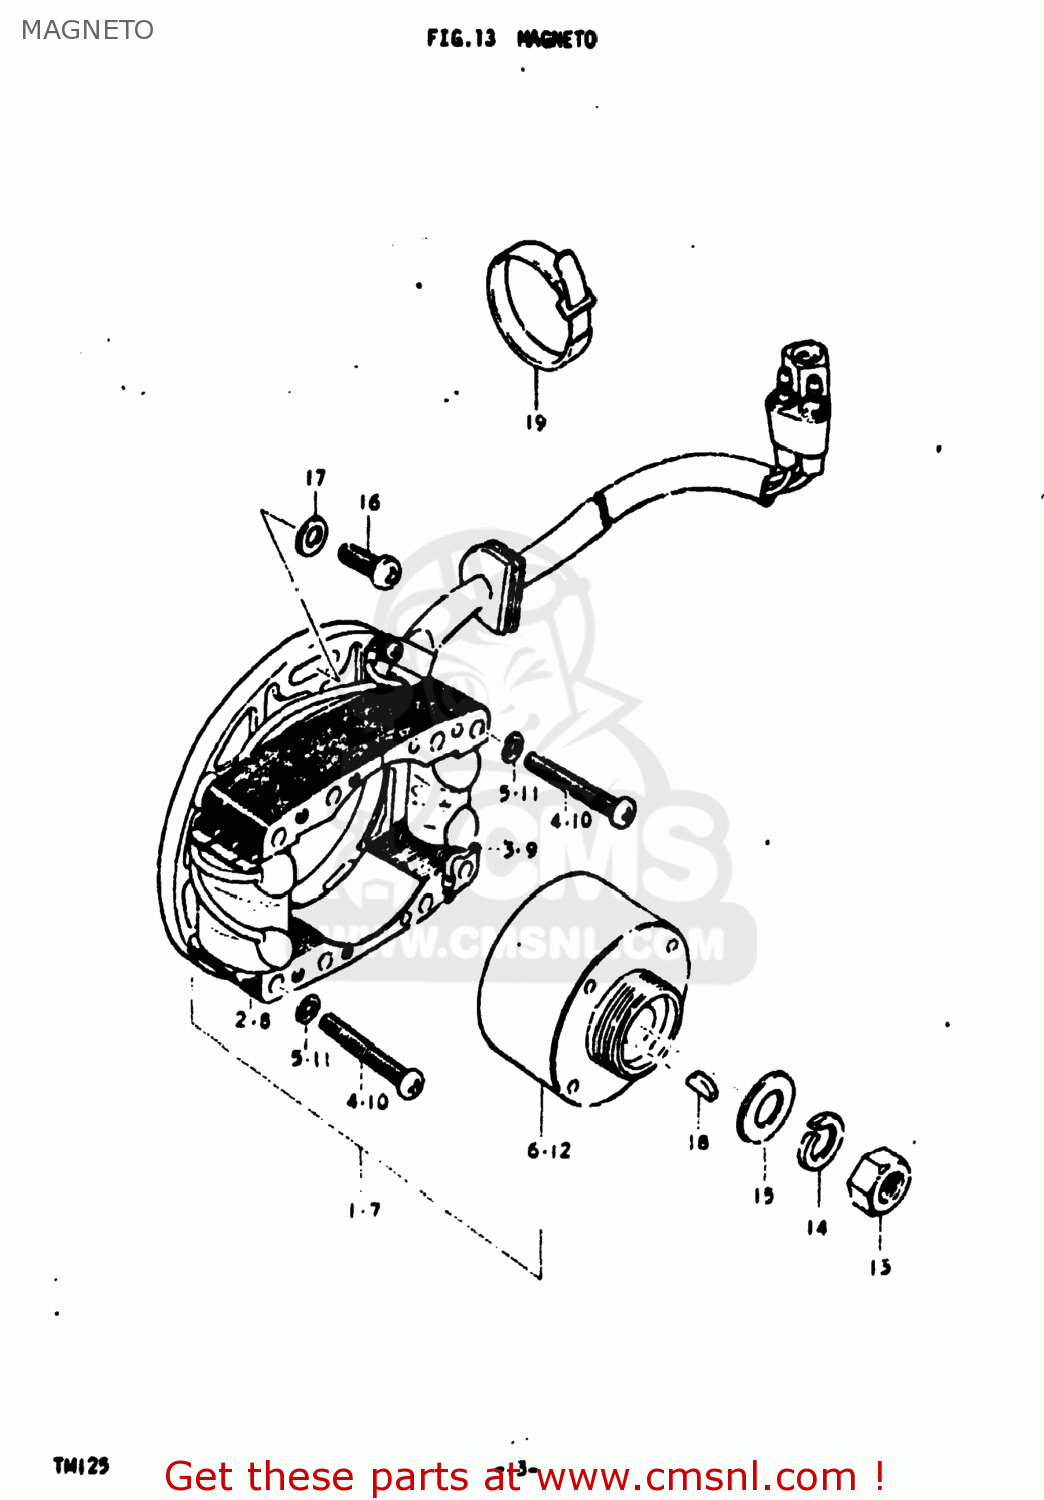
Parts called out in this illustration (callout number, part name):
1	MAGNETO ASSEMBLY
2	COIL
3	COIL,PULSER
4	SCREW
5	LOCK WASHER
6	ROTOR ASSEMBLY
7	MAGNETO ASSEMBLY
8	COIL
9	COIL,PULSER
10	SCREW
11	LOCK WASHER
12	ROTOR ASSEMBLY
13	NUT (10MM)
14	LOCK WASHER
15	WASHER
16	SCREW
17	WASHER
18	KEY
19	CLAMP L:110
